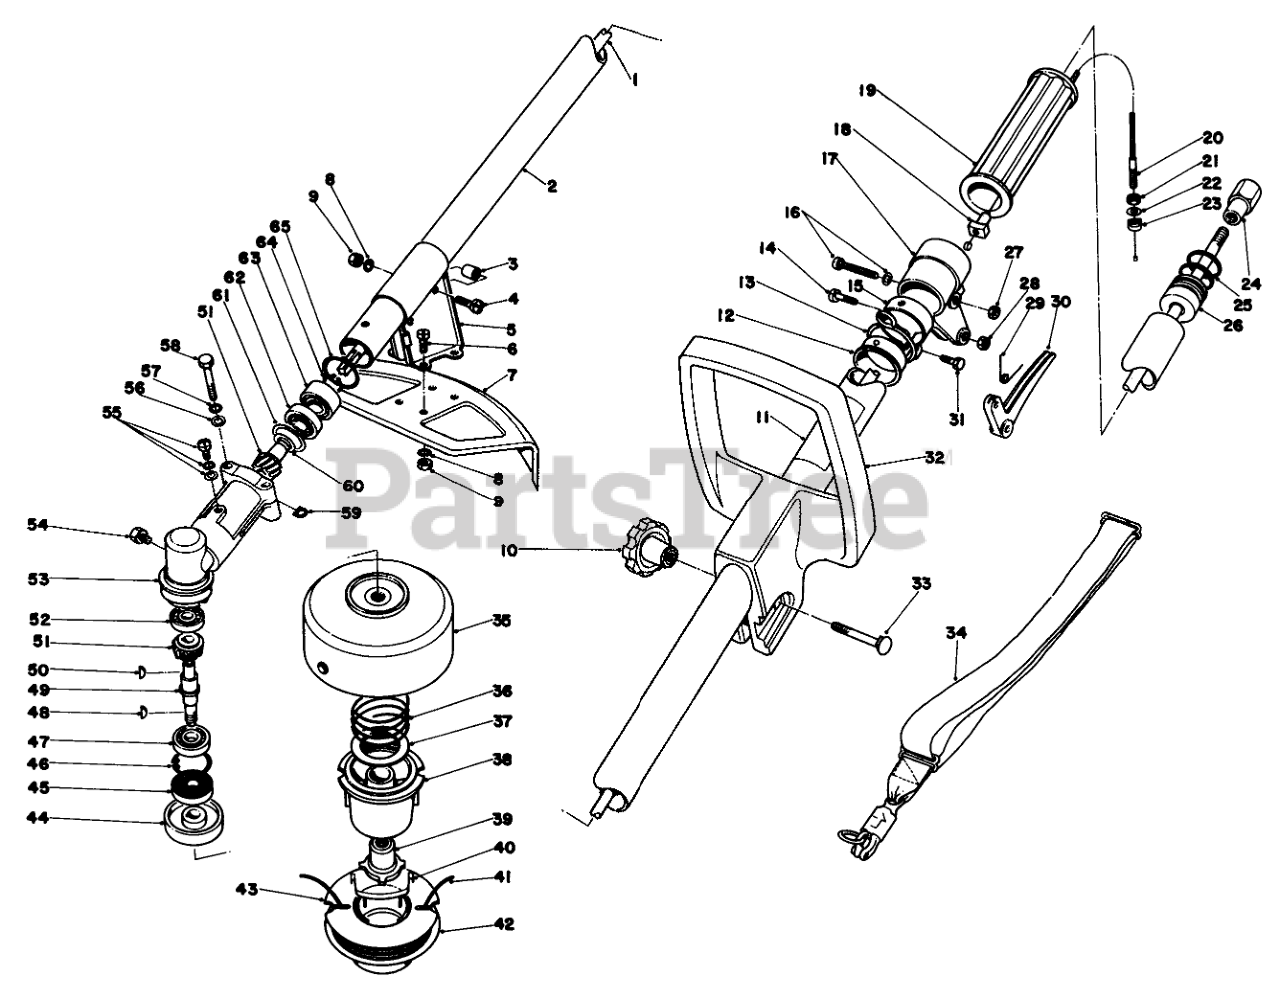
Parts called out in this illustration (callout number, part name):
1	Drive Shaft
2	Housing, Drive Shaft
3	Spacer
4	Screw
5	Bracket-Head Guard
6	SCREW
7	Shield
8	Washer
11	Decal Warning
12	Collar
13	Swivel Hook
14	Screw
15	Clamp
16	SCREW
17	Bracket, Throttle Trigger
18	SPACER
19	Hand Grip
20	THROTTLE CABLE
22	Washer
23	Locknut
24	Coupler
25	O-Ring
26	Bushing
27	Nut
29	Spring Return
30	Throttle Trigger
32	Adjustable Handle
33	BOLT-CARR
34	Shoulder Strap W/Ring
35	Drum Assembly
36	SPRING
37	WASHER-FLAT
38	SPOOL CORE
39	LH DRIVER
40	SADDLE-SPOOL CAP
41	#1 BULK SPOOL .095
42	Empty SPooI
43	Line Prewound On Spool (Incl. Item #4042)
44	Plate-Blade Fixing
45	Oilseal
46	Circlip
47	Ball Bearing
48	Woodruff Key
49	Shaft-PTO
50	Woodruff Key
51	Gear Set
52	Ball Bearing
53	Gear Housing
55	SCREW
56	WASHER
57	Washer
59	Spacer
60	Washer
61	Washer
62	Ball Bearing
63	Ball Bearing
64	Circlip
65	Circlip
